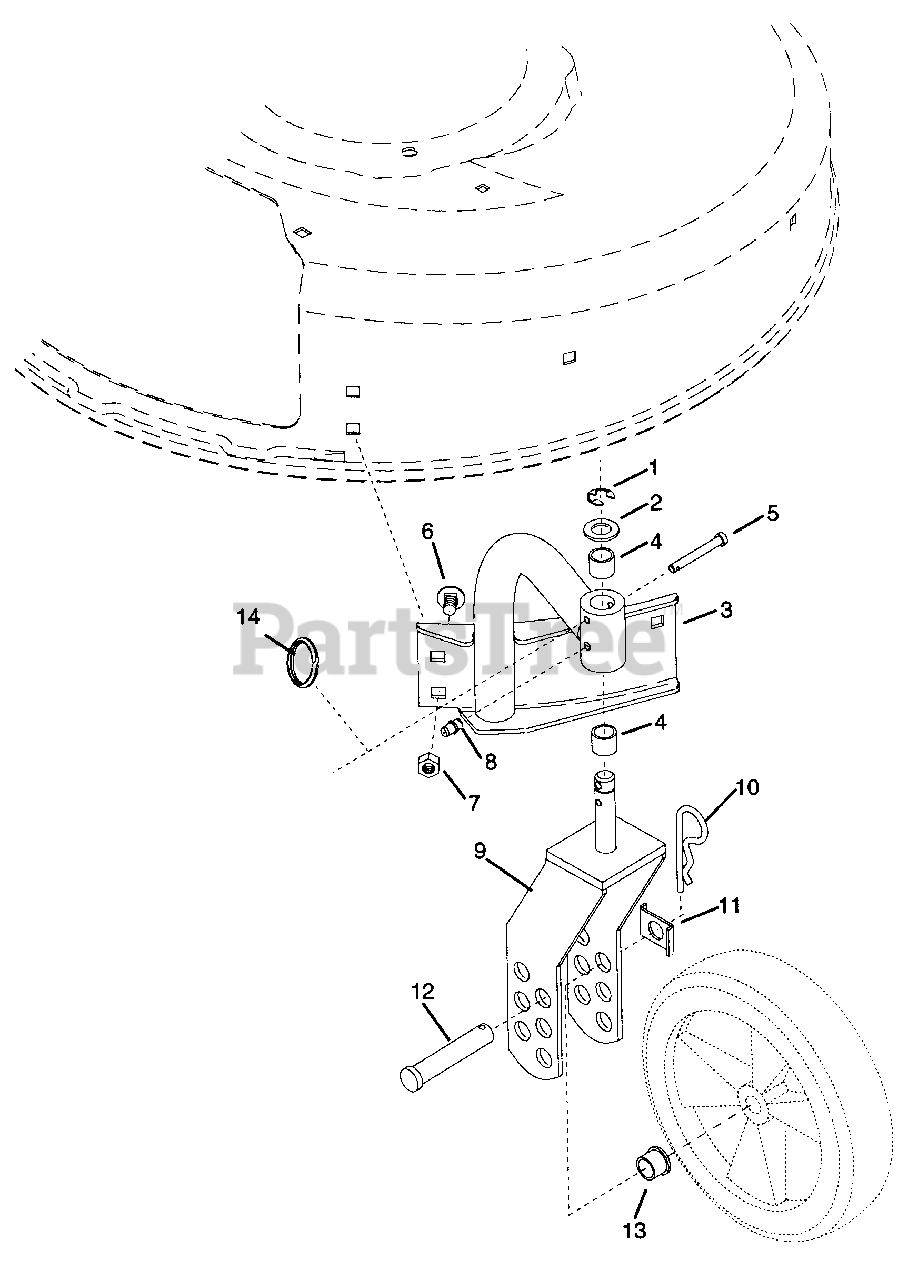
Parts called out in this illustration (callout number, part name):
1	RG-RTNG-EXT .625X.042
2	WSHR-FL-STL .630X1.005X.062 PL
3	RIGHT MOUNT ARM WELDMENT
4	BSHG-SLV .625X.750X.500 BR
5	PIN-CLEV .25X1.75
6	BLT-RDHDSQSHNK .31-18X.50 YZ
7	NUT-FLG. .312-18 PL
8	FTG-LUBE .25-28X.256 YWZC
9	WHEEL YOKE WELDMENT
10	PIN-HAIR INT .14X.4X2.75
11	AXLE TAB
12	PIN-CLEV .494X2.62 YWZC
13	BSHG-FLG .500X.625X.500X.750
14	KICKOUT RING YWZC
